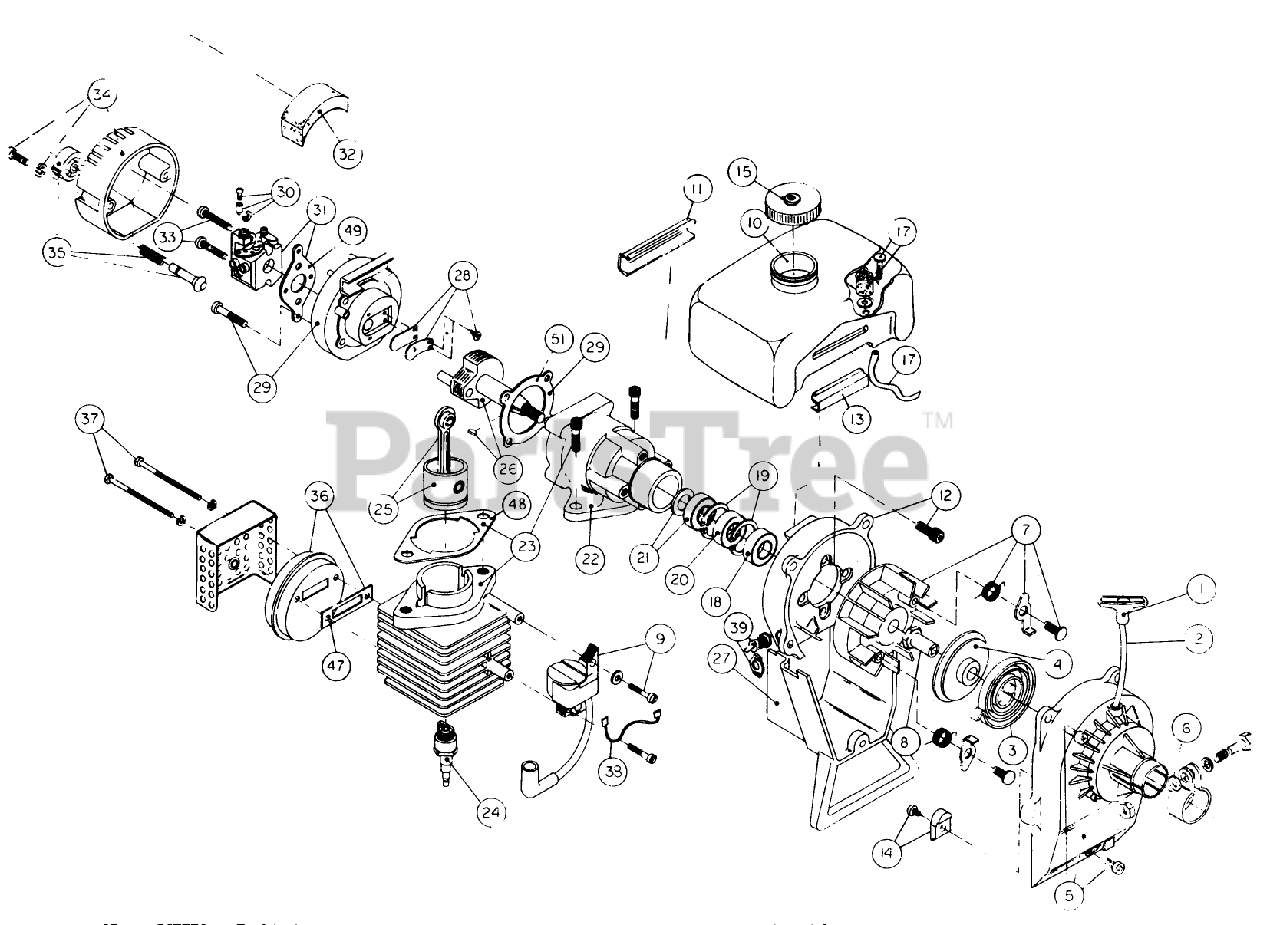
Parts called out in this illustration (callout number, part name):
8	SQUARE DRIVE NUT
10	Fuel tank
13	FRONT MOUNTING PAD
17	FUEL LINE ASM
18	OUTER BEARING
21	INNER BEARING ASM
24	SPARK PLUG
30	THROTTLE ADJ ASM
37	MUFFLER MOUNTING BOLTS
39	SWITCH ASM
